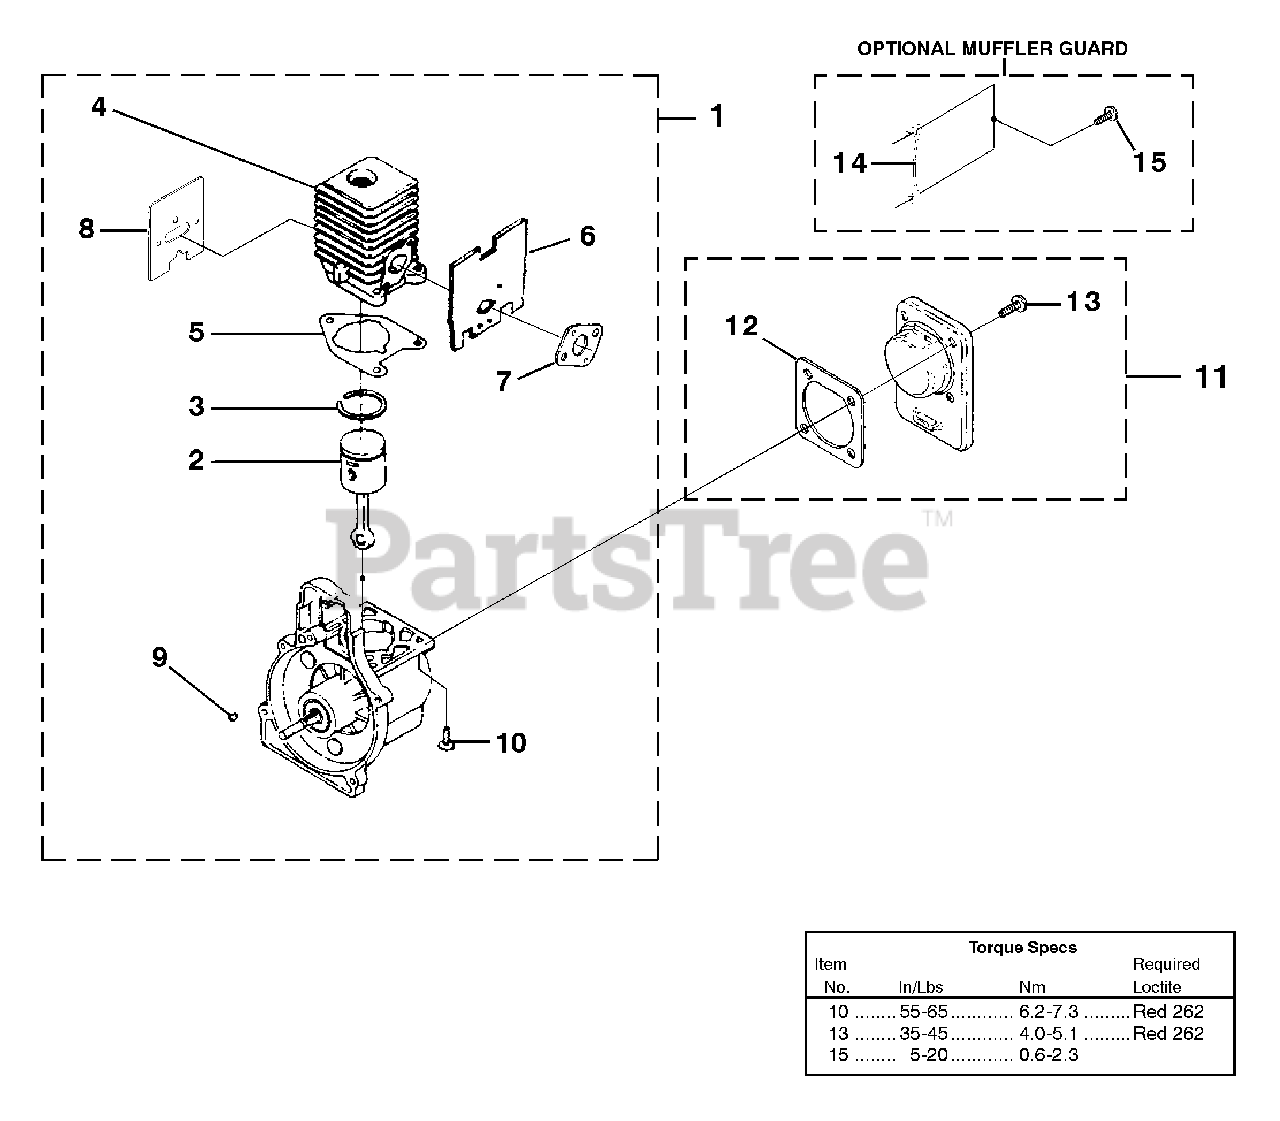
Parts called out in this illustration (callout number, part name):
1	SHORT BLOCK
2	PISTON & ROD ASSY.
3	RING-Piston
4	CYLINDER ASSY.
5	GASKET-Cylinder
6	GASKET-Heat Dam
7	GASKET-Carburetor
8	GASKET-Muffler
9	KEY-Woodruff
10	SCREW (12-24 X .660")
11	CRANKCASE COVER ASSEMBLY
12	GASKET-Crankcase Cover
13	SCREW-Sems (10-24 X 1/2")
14	MUFFLER GUARD
15	SCREW-Thread Forming (10-14 X 1/2")
